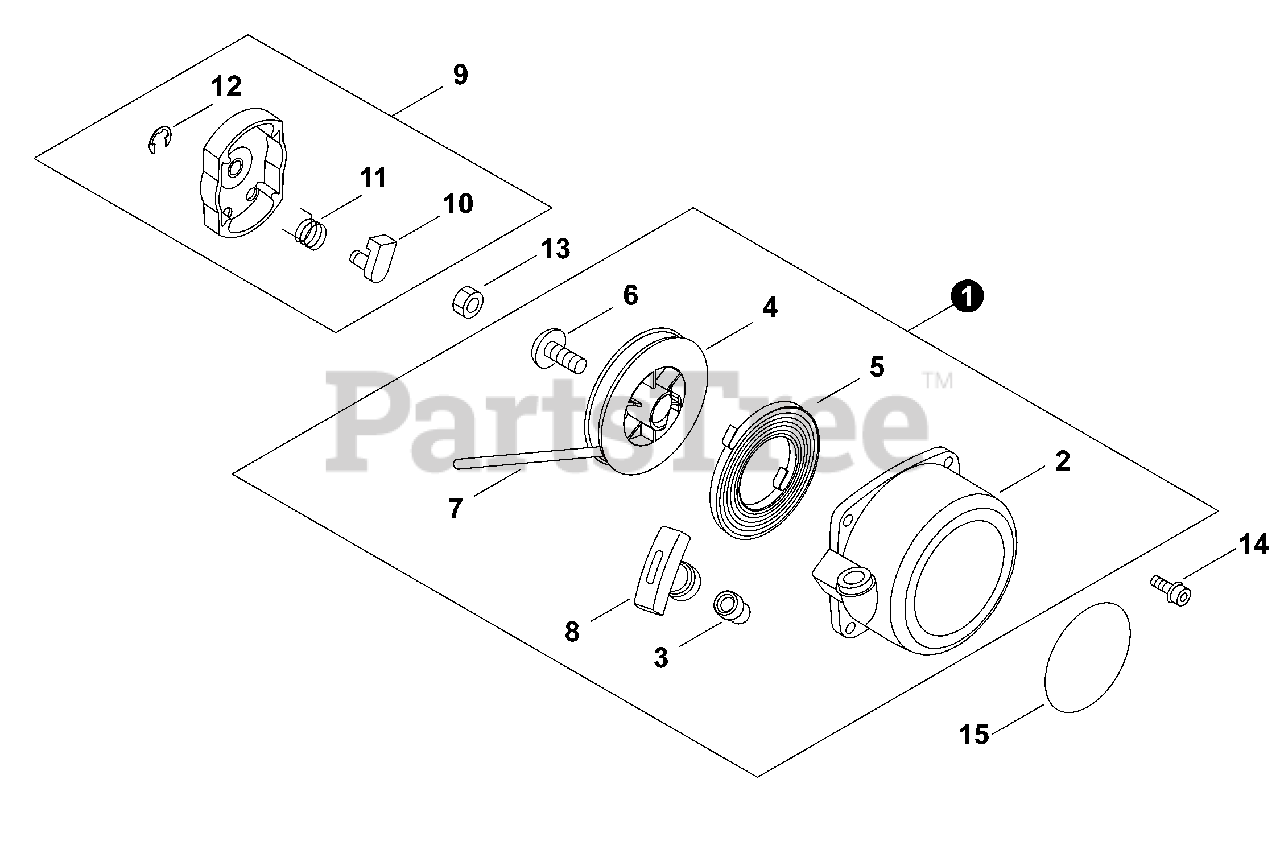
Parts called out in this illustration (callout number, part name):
1	STARTER ASSY, RECOIL
2	CASE, STARTER
3	GUIDE, ROPE
4	REEL, ROPE
5	SPRING, RECOIL
7	ROPE, STARTER 3.8×1150
8	GRIP, STARTER
9	PULLEY ASSY, STARTER
10	PAWL, STARTER
11	SPRING, RETURN
12	E-RING 4
13	NUT 8×1.25
14	BOLT 5×20
15	LABEL, RECOIL STARTER
